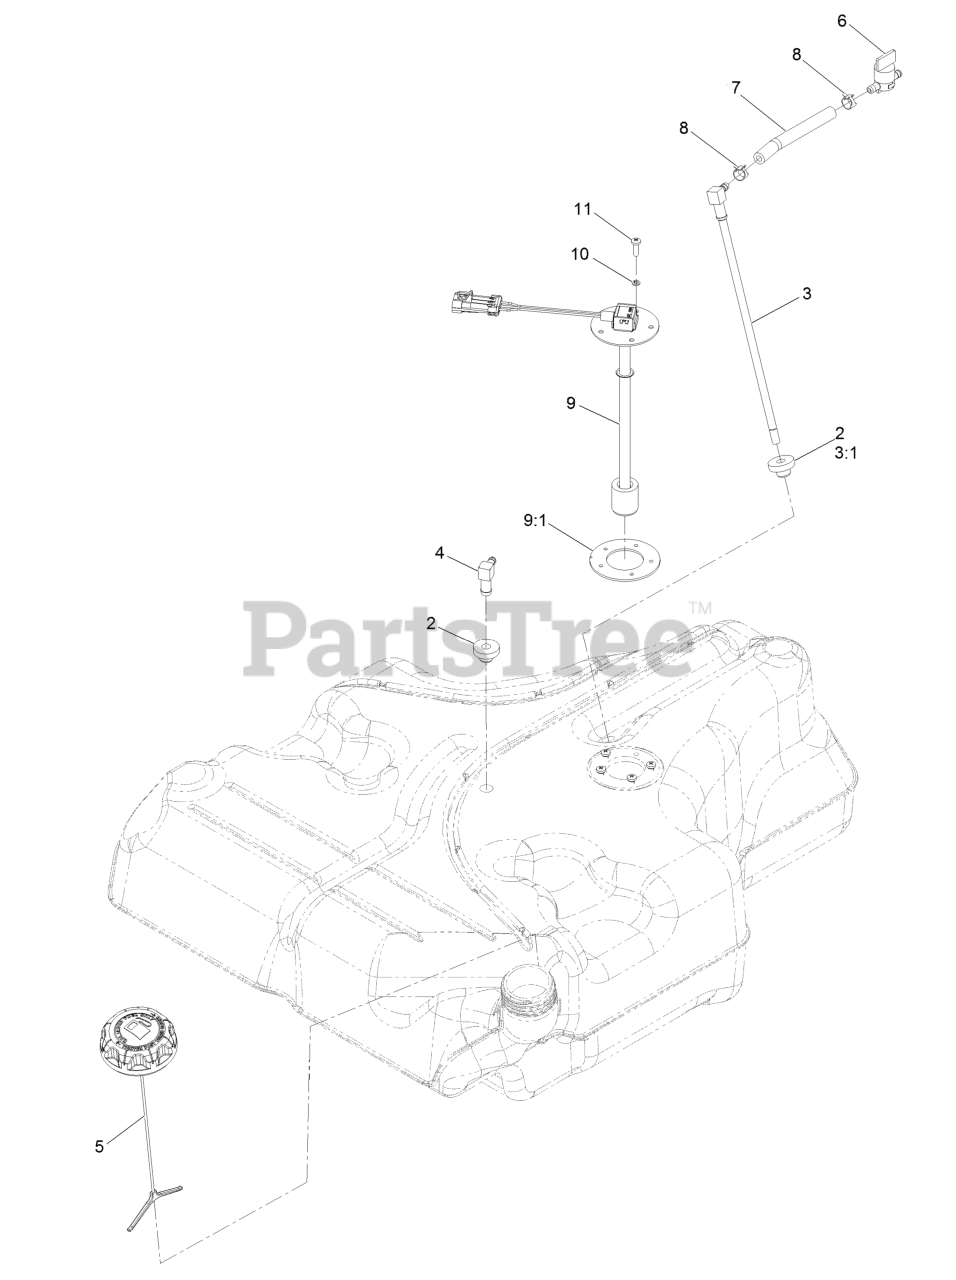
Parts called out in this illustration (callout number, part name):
2	BUSHING
3	FUEL LINE KIT (WITH GROMMET)
3:1	BUSHING
4	FITTING-90 ELBOW
5	CAP-FUEL, RATCHETING
6	VALVE-FUEL
7	HOSE-FUEL
8	CLAMP-HOSE
9	SENDER-LEVEL, FUEL (W/GAS
9:1	Gasket-Sender
10	WASHER-LOCK
11	SCREW-PPH
